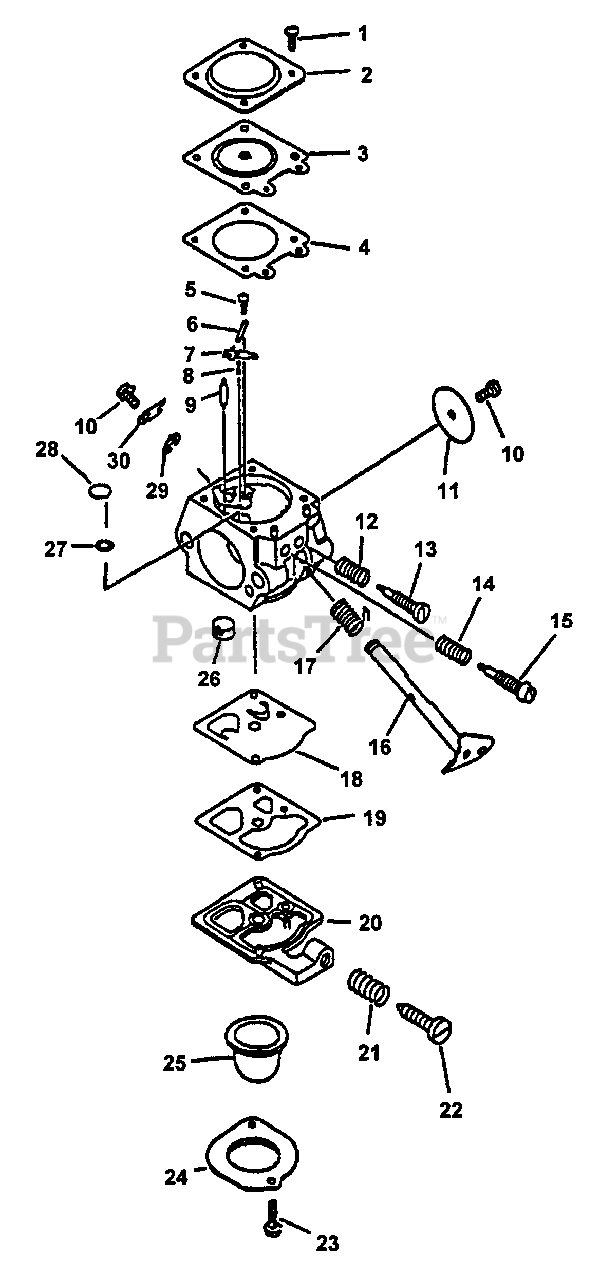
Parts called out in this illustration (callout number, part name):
2	COVER, METERING DIAPHRAGM
3	DIAPHRAGM, METERING
4	GASKET, METERING
5	SCREW, METERING LEVER PIN
6	PIN, METERING LEVER
7	LEVER, METERING
8	SPRING, METERING LEVER
9	VALVE, INLET NEEDLE
11	VALVE, THROTTLE WT-274
13	NEEDLE, LOW SPEED
15	NEEDLE, HIGH SPEED
16	SHAFT ASSY, WT-274 THROTTLE
17	SPRING, THROTTLE RETURN
20	COVER, PUMP
21	SPRING, IDLE ADJUST
22	SCREW, IDLE ADJUST
24	RETAINER, PURGE BULB
25	BULB, PURGE
26	STRAINER
27	RING, RETAINING
28	PLUG, WELCH
30	LEVER, THROTTLE
